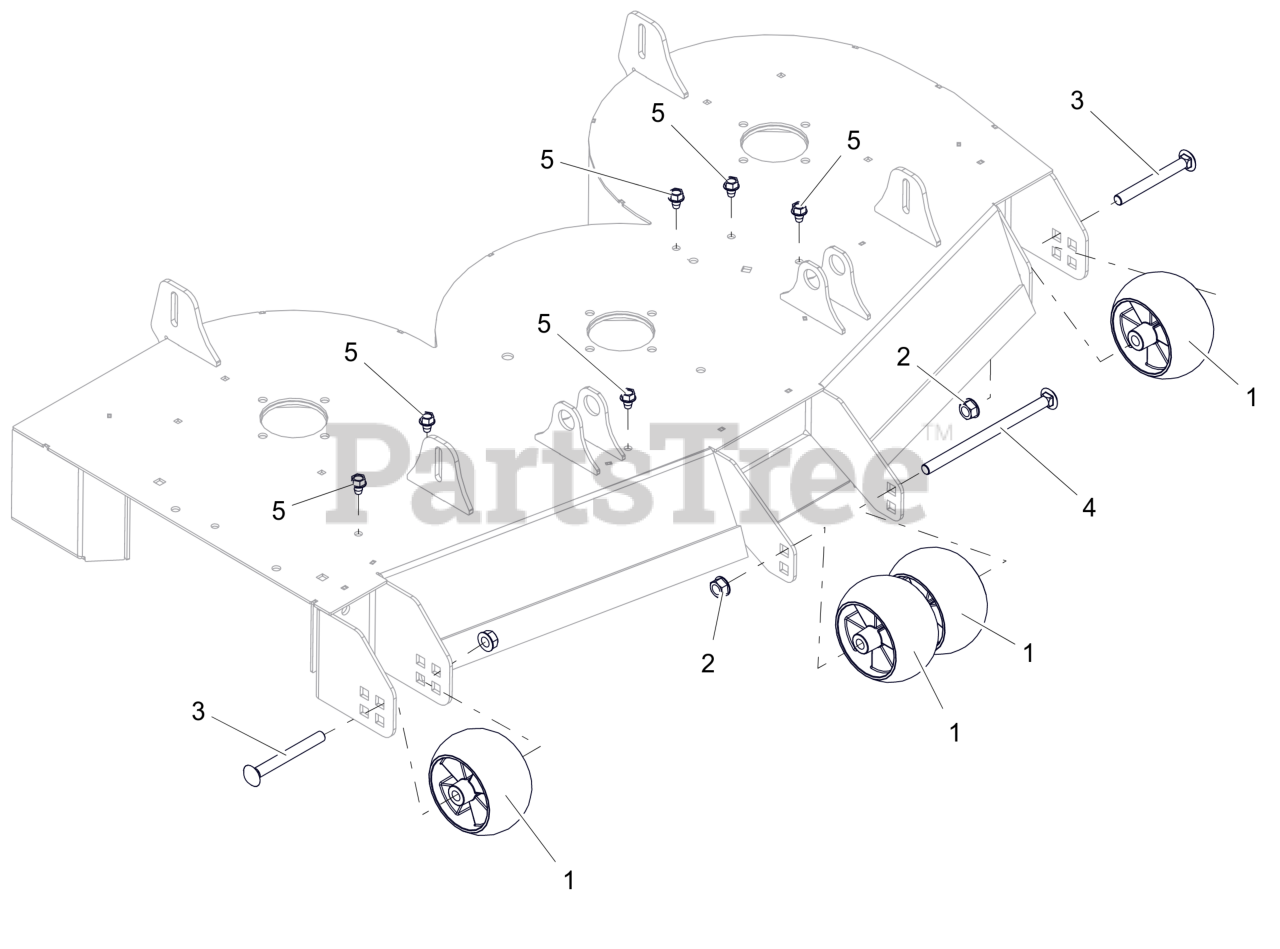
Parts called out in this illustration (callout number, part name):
1	WHEEL, ANTI SCALP - 5X3 CTR W/RIBS
2	NUT-LK-CTR-FLG .500-13 GG ZCC
3	BLT,RHNS .50-13X4.50 G5 ZCC NS
4	BLT,RHSN .50-13X8.00 G5 ZCC NS
5	SCR,TAP .375-16X.50 HWH TR ZCC
